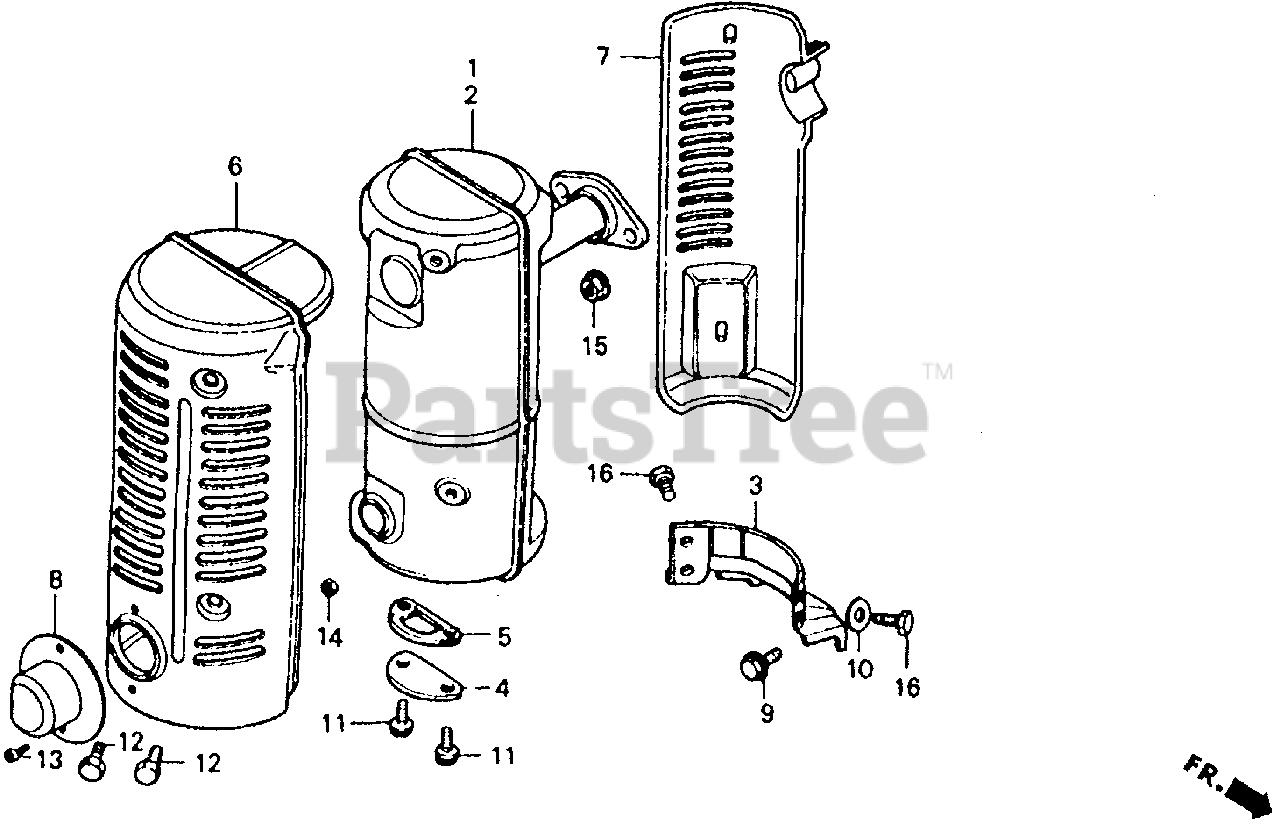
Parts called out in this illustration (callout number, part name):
1	MUFFLER ASSY.
2	MUFFLER
3	STAY, MUFFLER
4	LID, MUFFLER
5	GASKET, MUFFLER LID
6	PROTECTOR A, MUFFLER
7	PROTECTOR B, MUFFLER
8	DEFLECTOR, EX. MUFFLER
9	BOLT, FLANGE (8X16)
10	WASHER (8MM)
11	BOLT, HEX. (6X12)
12	BOLT, HEX. (6X6)
13	SCREW, PAN (4X6) (NOT AVAILABLE)
14	NUT, HEX. (4MM)
15	NUT, FLANGE (8MM)
16	BOLT, FLANGE (6X10)
